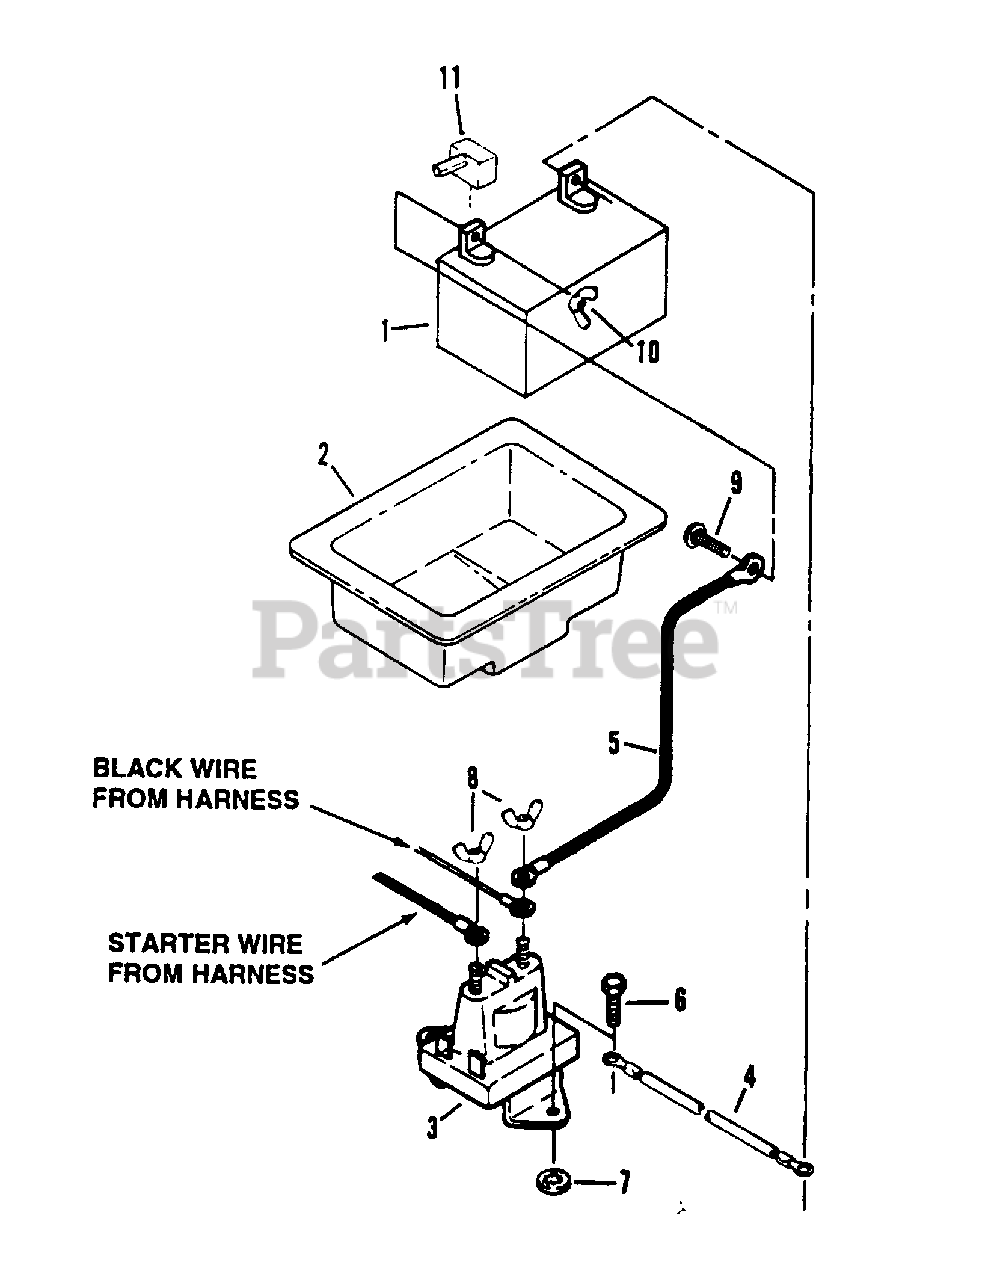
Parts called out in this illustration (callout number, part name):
1	KIT, Battery
2	TRAY, Battery
3	SOLENOID
4	CABLE, Ground (Black)
5	CABLE, Positive (Red)
6	SCREW, 1/4-20 x 1/2" Self-Tapping
7	RETAINER, 1/4 Bolt
8	NUT, 1/4-20 Locking Wing
9	BOLT, 1/4-20 x 3/4" Carriage
10	NUT, 1/4-20 Wing
11	COVER, Positive Terminal
